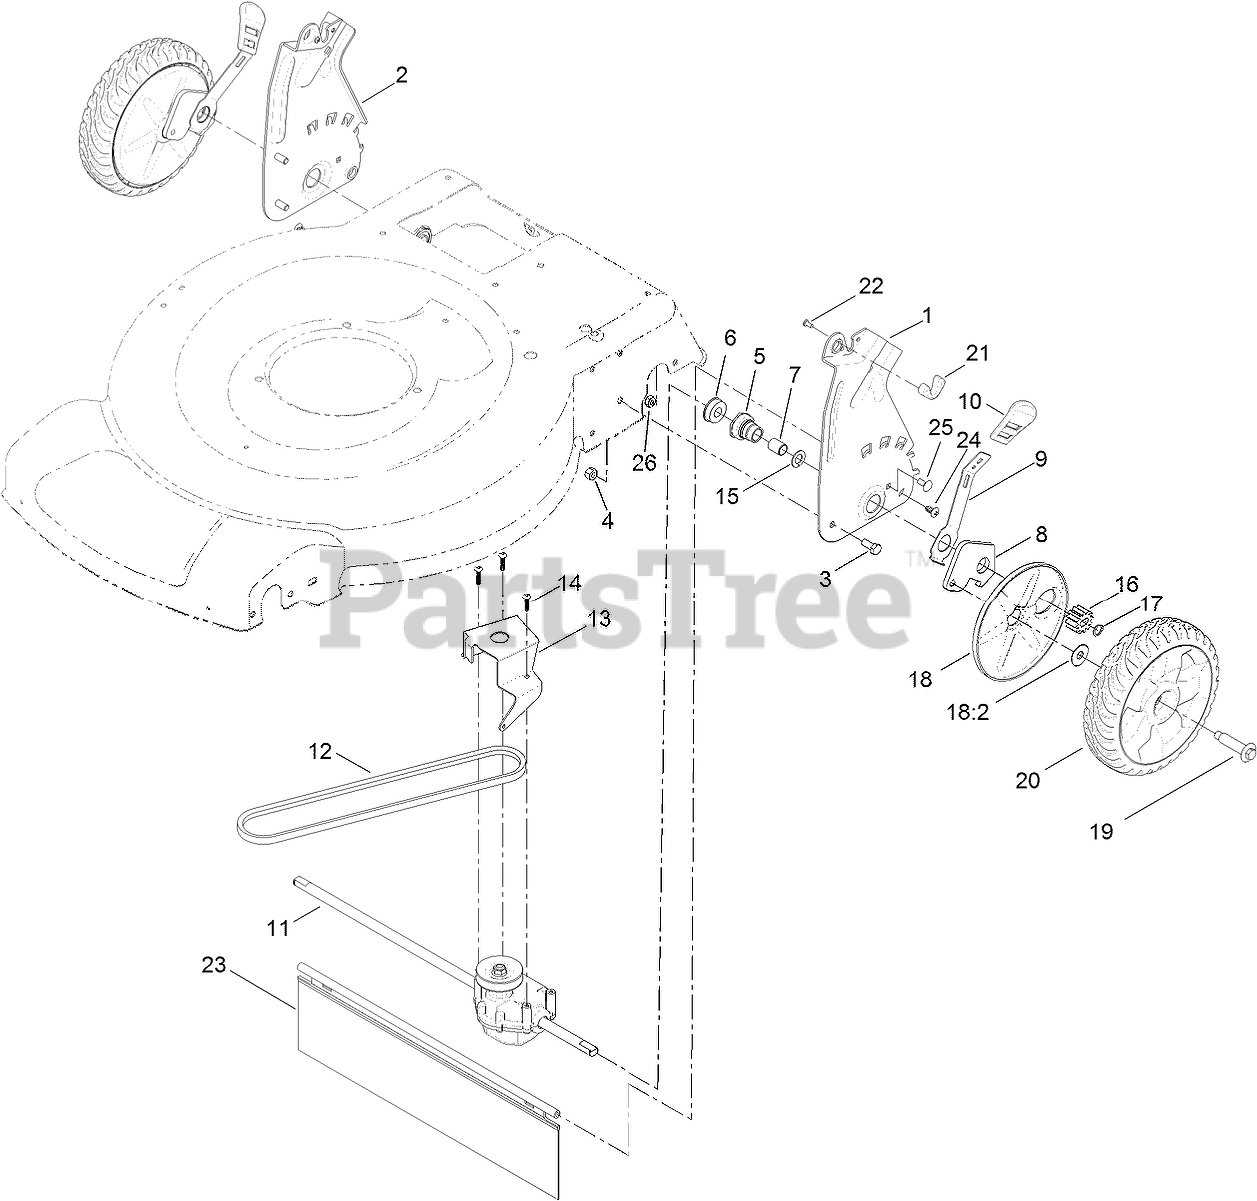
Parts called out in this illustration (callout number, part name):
1	PLATE-REAR, LH (HOC)
2	PLATE-REAR, RH (HOC)
3	SCREW-HH
4	NUT-LOCK, NI
5	RETAINER-BUSHING, HOC
6	BEARING-BALL
7	BUSHING-SLEEVE
8	ARM-PIVOT, REAR
9	ARM-SPRING
10	KNOB-HOC
11	TRANSMISSION ASM
12	BELT-V
13	BRACKET-TRANSMISSION
14	SCREW-PLASTITE
15	WASHER-THRUST
16	GEAR-PINION, 15T
17	RING-RETAINING
18	WHEEL COVER ASM
18:2	WASHER-STEPPED
19	BOLT-SHOULDER
20	8 INCH WHEEL GEAR ASM
21	ANCHOR-BAG
22	Screw-PPH
23	SHIELD-TRAILING
24	SCREW-PTH
25	SCREW-CARR
26	NUT-LOCK, NI
